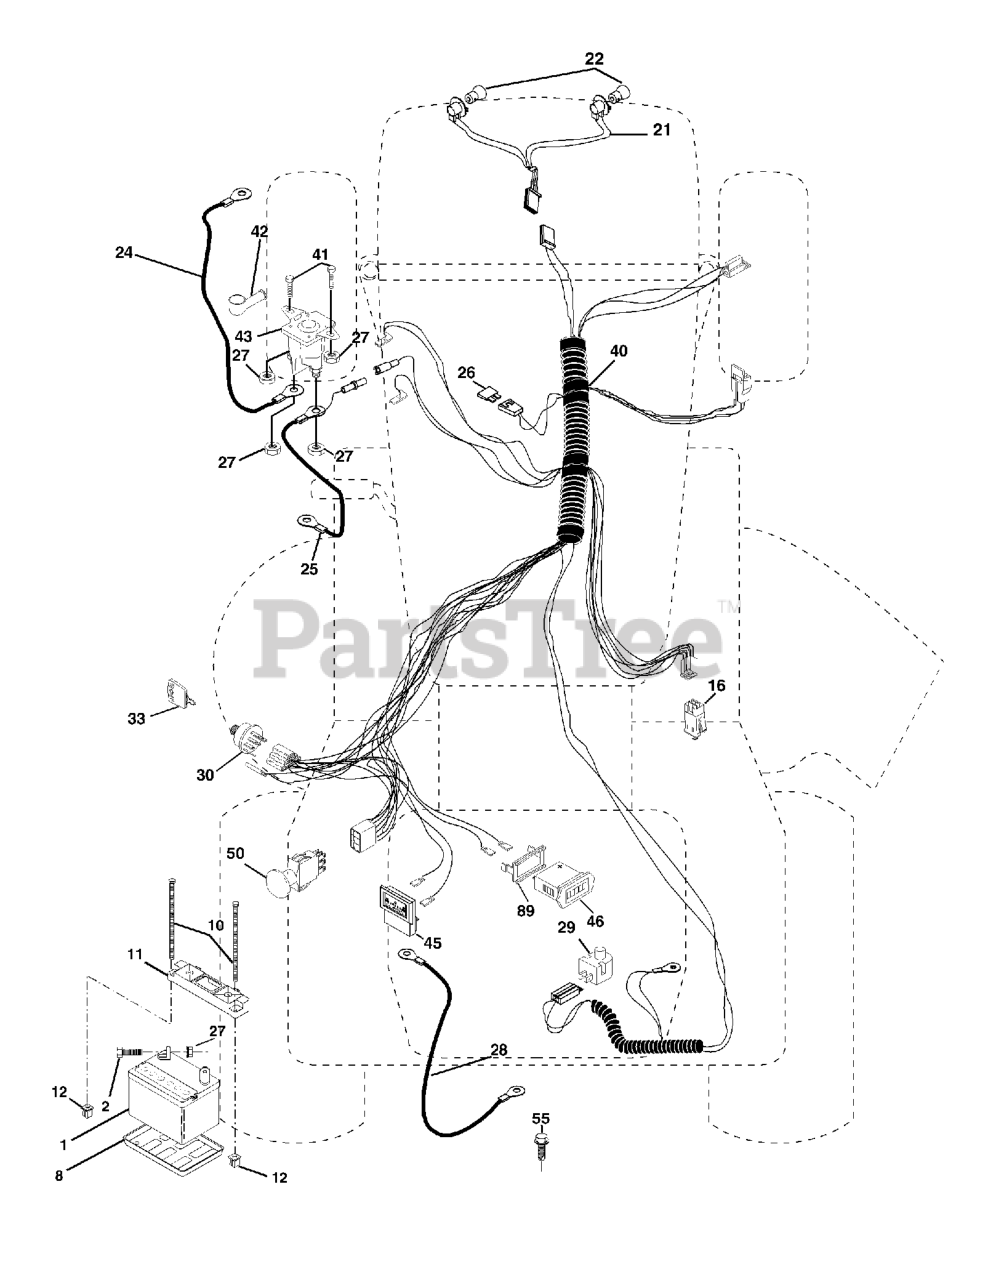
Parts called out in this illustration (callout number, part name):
1	BATTERY 12V .35 AMP
2	BOLT.HEX.1/4.X.3/4.DICHROMATE
8	BATTERY TRAY T
10	BOLT 1/4-20 X 7.5
11	BATTERY HOLDDOWN FRONT MOUNT
12	NUT, PUSH NYLON 1/4" BATTERY
16	SWITCH INTERLOOK PUSH-IN
21	HARNESS ASSY LIGHT
22	LIGHTBULB
24	BATTERY CABLE GT
25	CABLE BATTERY 6 GA 22" W/16W
26	FUSE 20AMP
27	NUT
28	CABLE GROUND 6 GA 21" 90T BLK
29	RP.SWITCH.PLUNGER.NC.GRAY
30	IGNITION SWITCH
33	KEY MLD GEN DELTA
40	HARNESS.IGNITION
41	BOLT
42	TERMINAL COVER
43	SOLENOID
45	AMMETER
46	HOUR METER
50	RP.PTO.SWITCH.8 TERMINAL.BLACK
55	Screw 5/16-18 x 1/2 Hex, Self Tapping 5/16-18 x 1/2
89	BRACKET SNAP-IN HOURMETER
